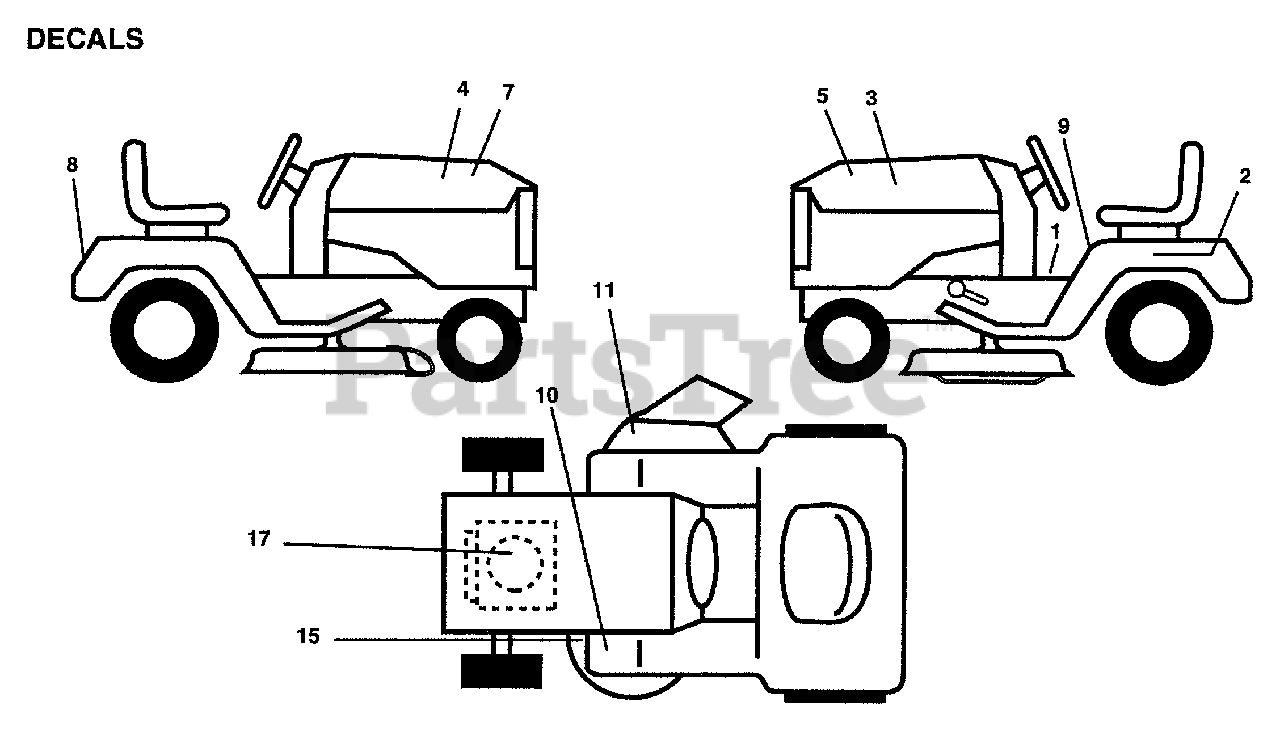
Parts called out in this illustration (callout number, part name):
1	Decal Instruction Dash Eng/fr
2	Decal Btry Dngr/Psn P/L Sym Ac
3	Decal Hood LH
4	Decal Hood RH
5	Decal Ins Hd LH
7	Decal Ins Hd RH
8	Decal Fender Husq
9	Decal Caution Fender Eng/fr
10	Decal Clutch/brake Eng/fr
11	Decal Warning Multi-Language
15	Decal V-Belt Schematic
17	Decal B & S 15.5 Diamond Engine
